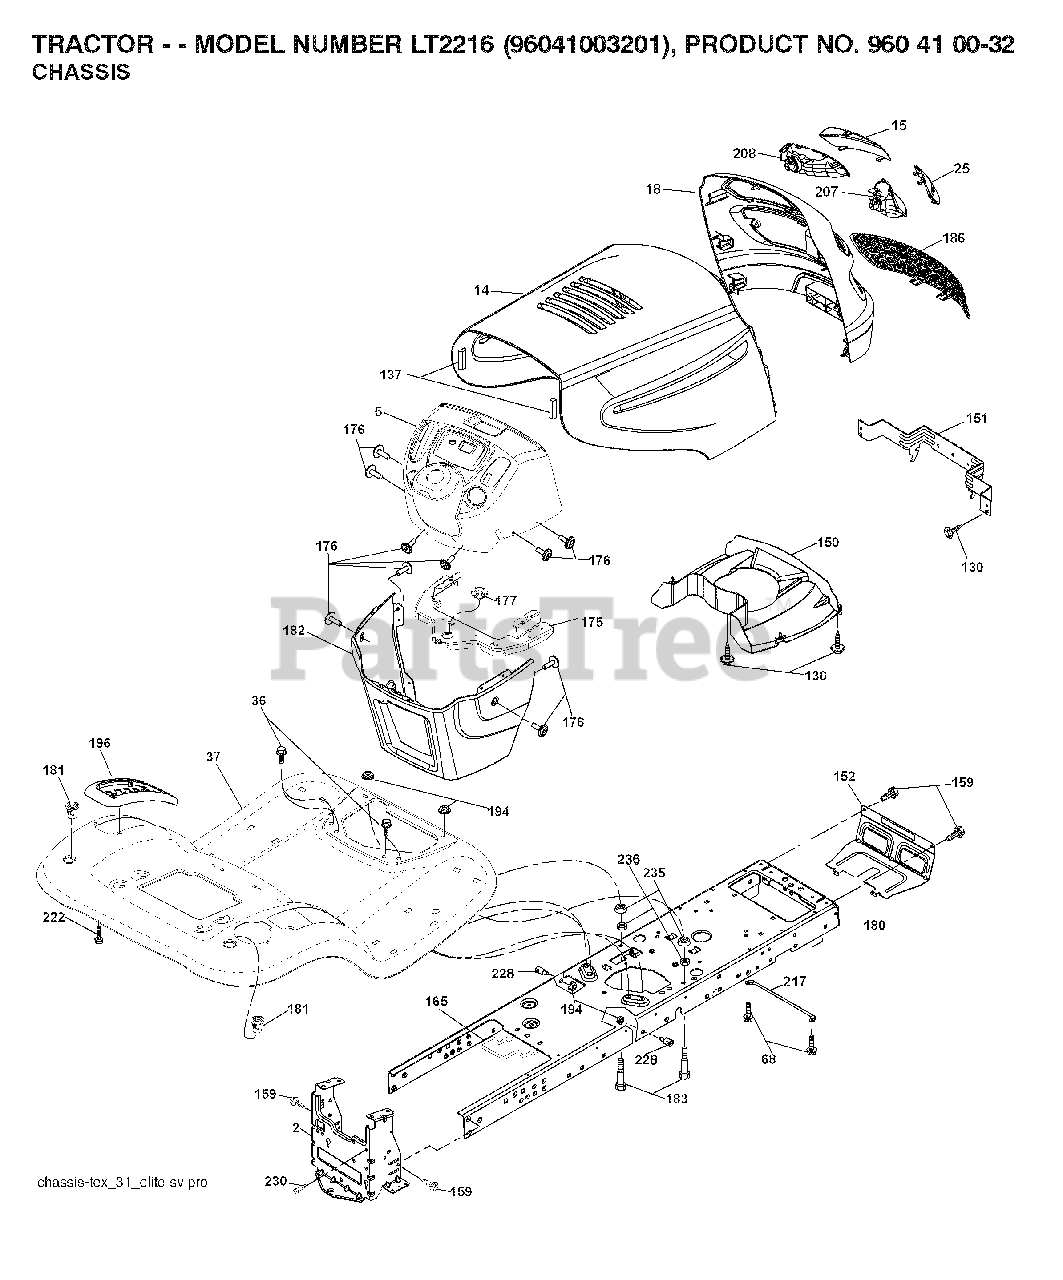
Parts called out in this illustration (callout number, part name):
2	DRAWBAR.1PC.NSTL
36	SCREW 5/16"
130	SCREW
137	BUMPER.HOOD.LARGE.1.75"
151	BRACKET PIVOT
152	SHIELD.BROWNING/DEBRIS
159	SCREW, 3/8-16X3/4
175	CROSSMEMBER.LT
176	SCREW.#10-24X5/8.RN.QU
177	BUSHING STEERING
180	CHASSIS.STAMPING.LT/GT
181	FEND/FTRST.PCH.CPH.NFW
182	DASH.LOWER.LT.CCS
183	BOLT.5/16-18X1-1/4 FULL.THREAD
194	NUT LOCK HEX FLANGE 5/16-18
196	CONSOLE.ASM.DECK.LIFT.TLT.BLAC
200	NUT.CENTERLOCK.5/16-
207	BEZEL GRILL RH
208	BEZEL GRILL LH
217	ROD PIVOT CHASSIS/HOOD
219	STUD.FASTNER.W/ANTI-ROTATE
222	SCREW.1/4-20X5/8
230	SHOULDER BOLT 5/16-18TT
235	SPACER FENDER
236	NUT.CENTERLOCK.5/16-
